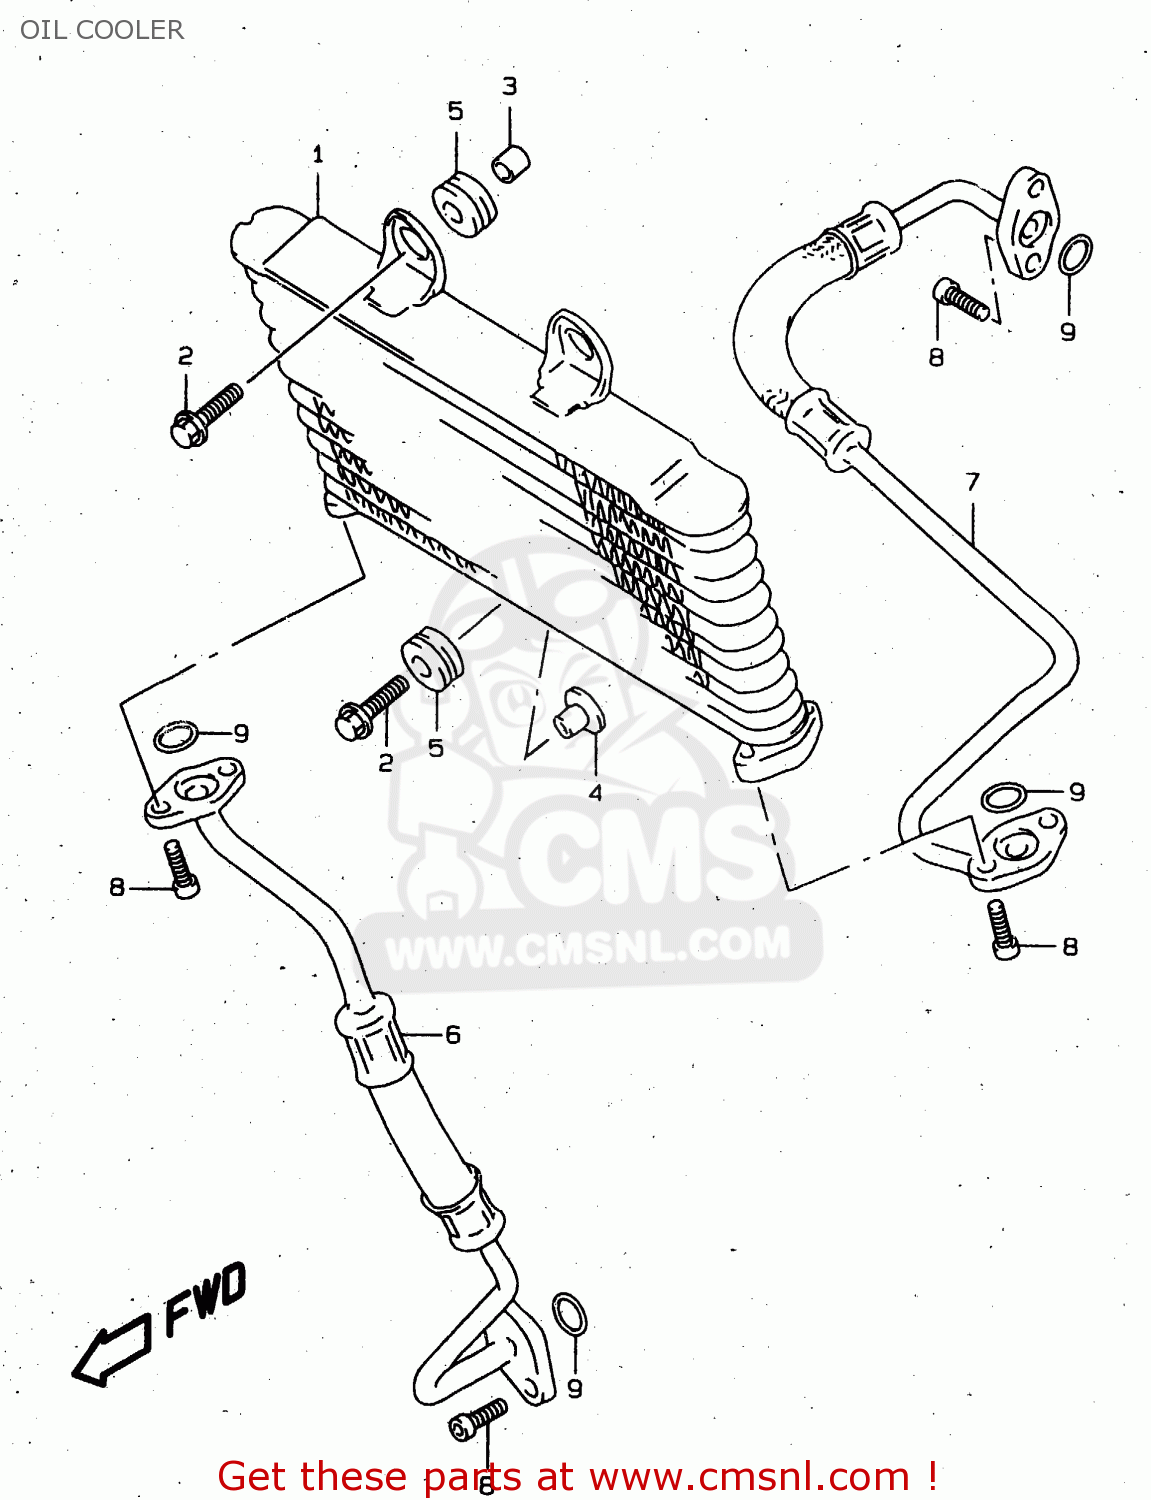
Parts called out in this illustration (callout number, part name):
1	COOLER ASSY,OIL
2	BOLT(6X30)
3	SPACER(6.5X10X10)
4	SPACER(6.5X10X11.6)
5	CUSHION
6	HOSE,OIL COOLER,R
7	HOSE,OIL COOLER,L
8	BOLT,OIL FILLE
9	O RING(D:2.4,ID:12.3)
